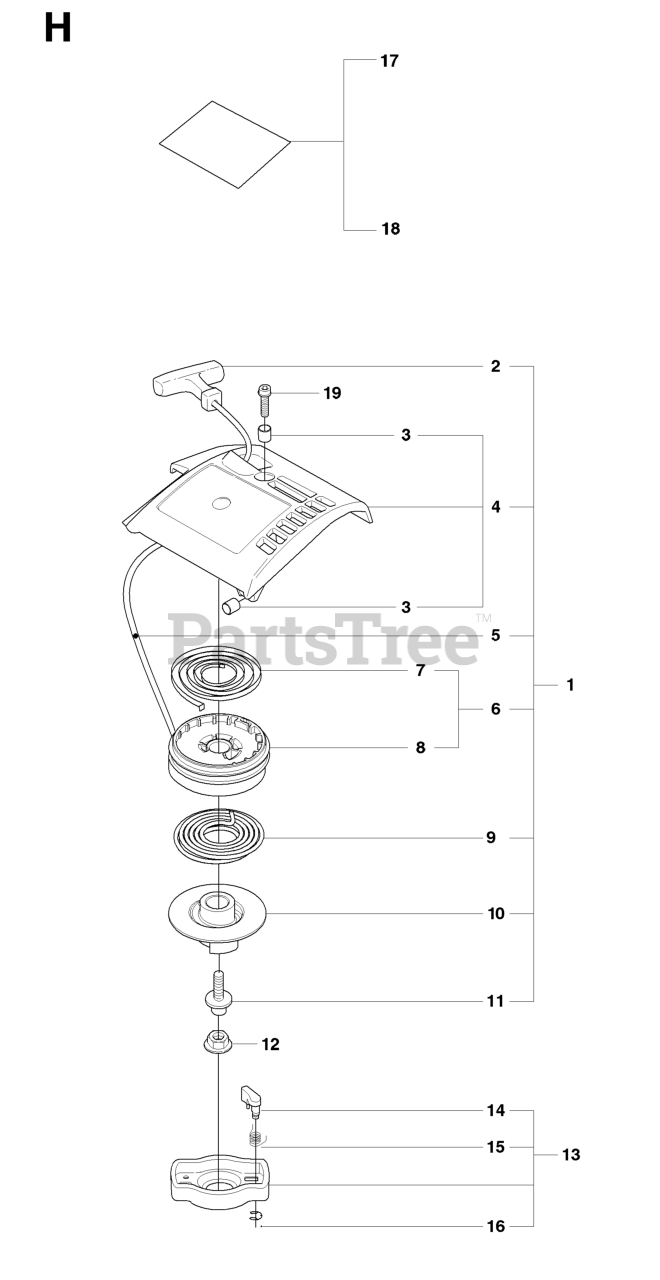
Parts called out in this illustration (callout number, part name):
1	RP STARTER ASSY
2	STARTER HANDLE
3	SPACING SLEEVE
4	STARTER HOUSING
5	STARTER ROPE
6	STARTER PULLEY
8	STARTER PULLEY
9	SPRING - DRIVER
10	DRIVER PULLEY
12	FLANGE NUT
13	PAWL ASSY COMPLETE
14	STARTER PAWL
